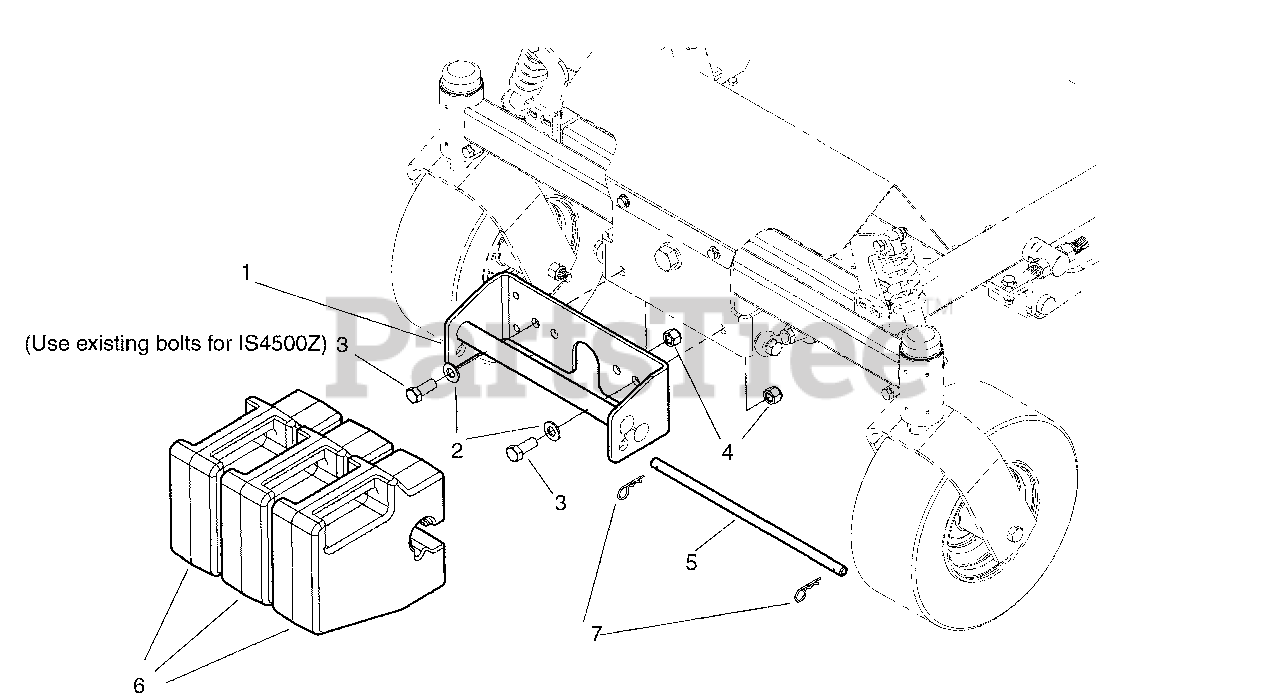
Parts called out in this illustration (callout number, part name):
1	HOLDER ASMY-WEIGHT CONS Z CAT - BLACK
2	WASHER, 1/2 SAE
3	BOLT, 1/2-20 X 1-1/4" GD5 YZ
4	NUT, 1/2-20 HEX NYLON LOCK
5	ROD-.500DIA 13.75LG YELLOW CON
6	WEIGHT-QUICK ATTACH 50LB SUITCAS PAINTED
7	PIN, HAIR, .0915 X 1-7/8
